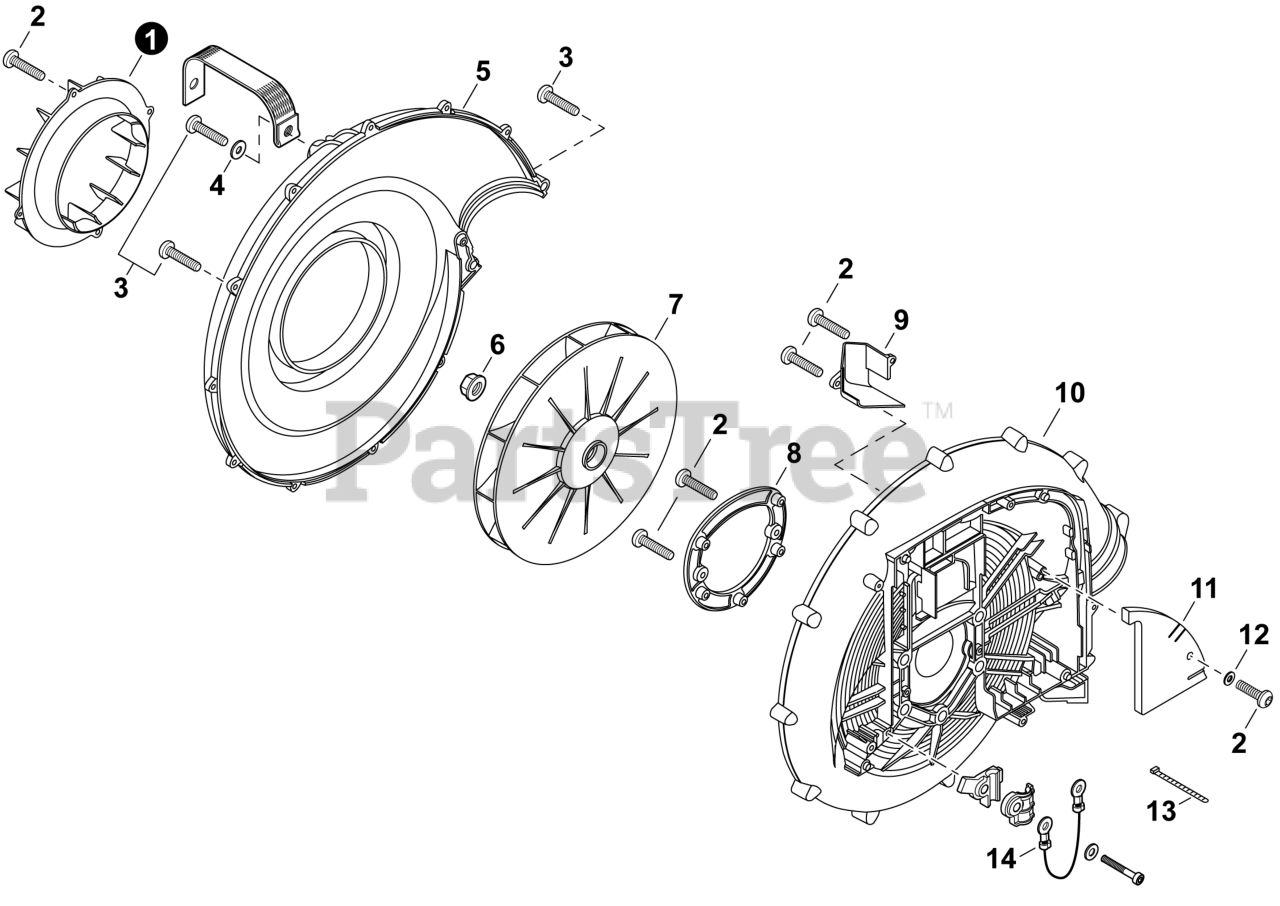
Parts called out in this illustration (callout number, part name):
1	DEFLECTOR, AIR
2	BOLT, TORX 5x16
3	BOLT, TORX 5x20
4	WASHER 5.5x16x2T
5	COVER, FAN
6	NUT, FLANGE 10x1.25
7	FAN, BLOWER
8	PLATE, ENGINE
9	COVER, AIR GUIDE
10	CASE, FAN
11	PAD, FOAM
12	WASHER 5.2x14xT3
13	STRAP, CABLE
14	LEAD L= 195 MM
